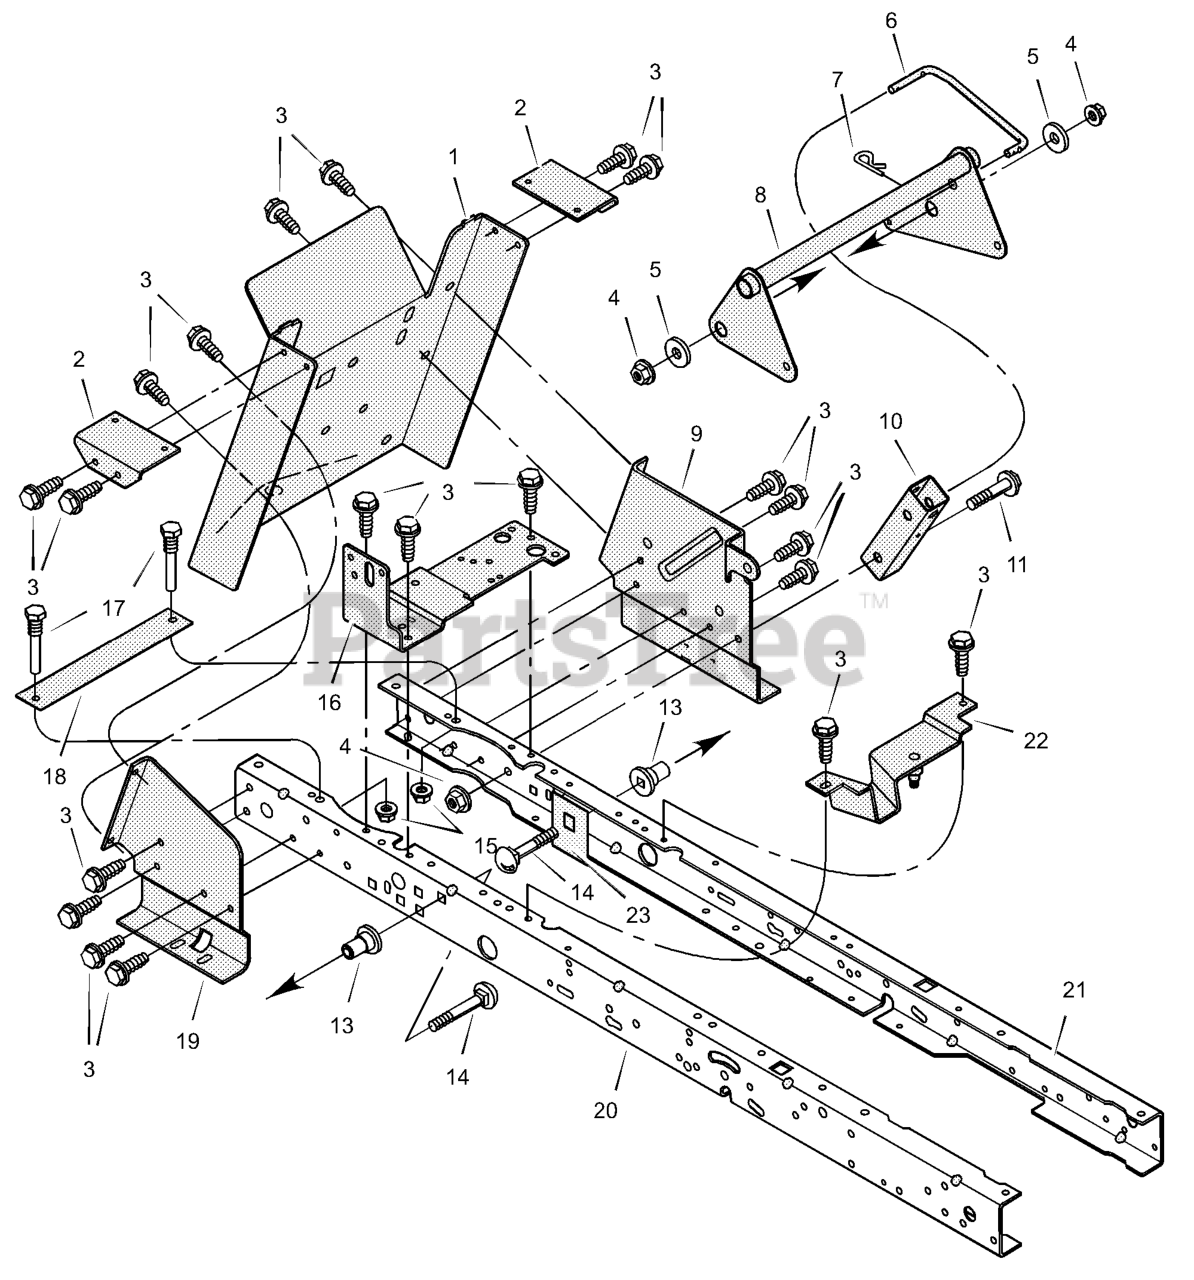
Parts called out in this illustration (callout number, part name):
1	Frame, Rear Hitch
2	Bracket, Seat Deck
4	Nut, Flange
6	Link, Lift Handle
7	Pin, Hair
8	Assembly, Lifter
9	Bracket, Left Transaxle
10	Bracket, Lift Pivot
11	Bolt, Shoulder
13	Spacer, Lifter
14	Bolt, Carriage
15	Nut, Flange
16	Bracket, Right Shift
17	Screw, Guide
18	Bracket, Battery Support
19	Bracket, Right Transaxle
20	Frame, Right
21	Frame, Left
22	Bracket, Idler
23	Plate, Stiffening
